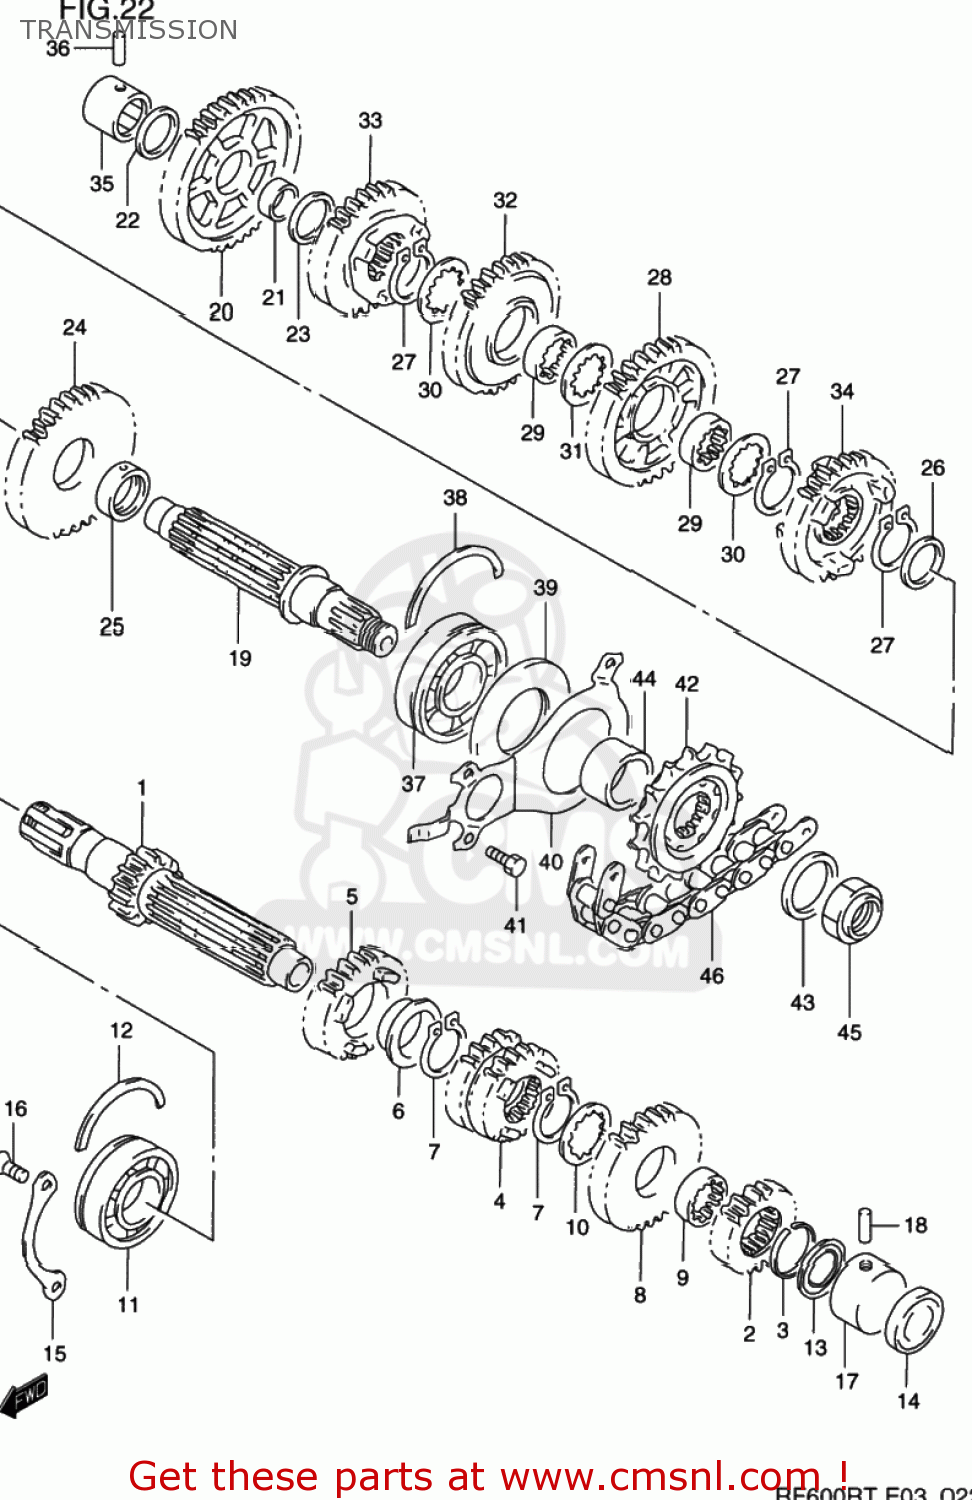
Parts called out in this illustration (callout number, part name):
1	SHAFT,COUNTER
2	GEAR,SECOND DRIVE
3	CIRCLIP
4	GEAR,THIRD & FOURTH DRIVE
5	GEAR,FIFTH DRIVE
6	BUSH(28X32X2)
7	CIRCLIP
8	GEAR,SIXTH DRIVE
9	BUSHING,SIXTH DRIVE GEAR
10	WASHER,LOCK
11	BEARING(25X62X17)
12	C-RING
13	SEAL,OIL(20X31.2X2.7)
14	CAP,COUNTER SHAFT,L
15	RETAINER,CNTR SHAFT BEARING
16	SCREW ,6X16
17	BEARING(20X34X17.5)
18	PIN
19	SHAFT,DRIVE
20	GEAR,1ST DRIVEN
21	BUSH(22X26X9)
22	WASHER
23	WASHER
24	GEAR,2ND DRIVEN
25	BUSH(28X32X9.5)
26	WASHER, THRUST
27	CIRCLIP
28	GEAR,3RD DRIVEN(NT:33)
29	BUSH,3RD DRIVEN GEAR
30	WASHER,LOCK
31	WASHER,LOCK
32	GEAR,FOURTH DRIVEN
33	GEAR,5TH DRIVEN(NT:29)
34	GEAR,6TH DRIVEN
35	BEARING(20X34X20)
36	PIN
37	BEARING(28X70X18)
38	C RING
39	SEAL,OIL(34.8X70X6)
40	RETAINER,DRIVE SHAFT OIL SEAL
41	BOLT
42	SPROCKET,ENGINE(14T)
43	WASHER,THRUST
44	SPACER(25X36X17.7)
45	NUT
46	CHAIN ASSEMBLY,DRIVE 108LE
